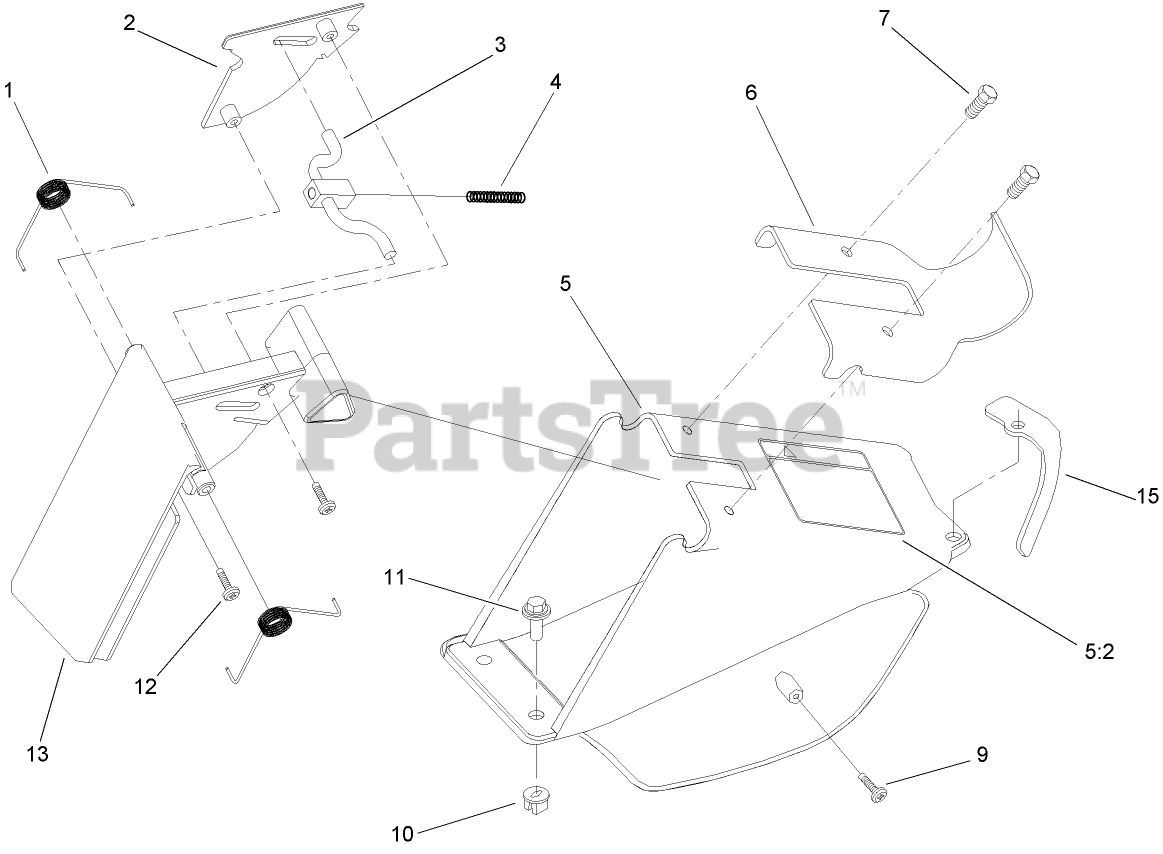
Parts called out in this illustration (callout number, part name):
1	SPRING-DOOR, RH
2	DOOR COVER
3	LATCH-DOOR
4	SPRING-COMPRESSION, LATCH
5:2	DECAL-DANGER
7	SCREW-PLASTITE
9	SCREW-PPH
10	NUT-CLIP
11	SCREW-HWH
13	DOOR-DISCHARGE
15	CLAMP-DOOR
